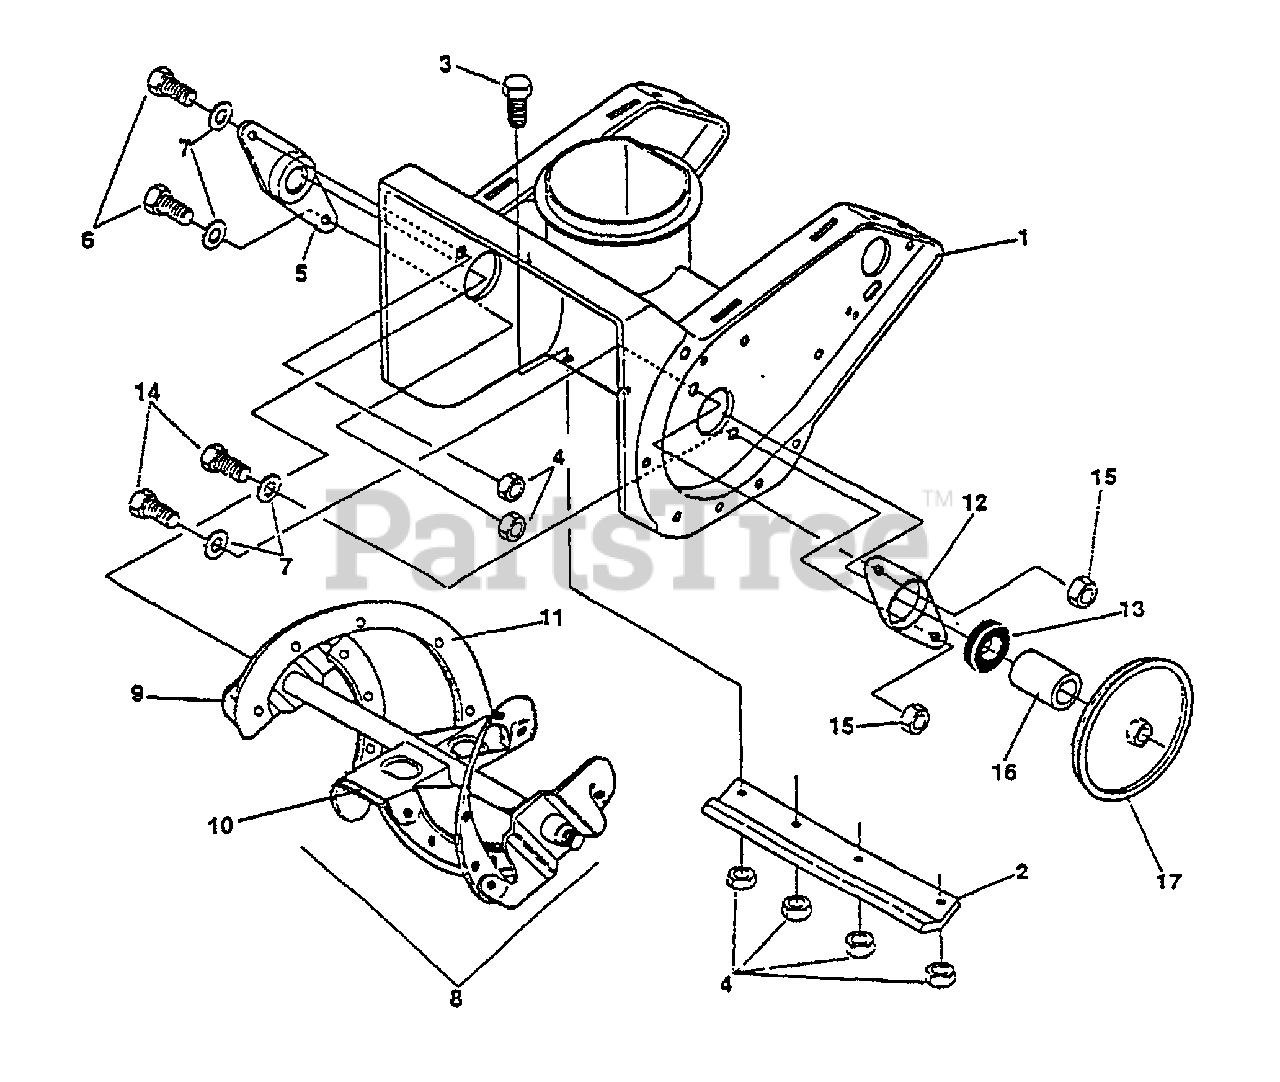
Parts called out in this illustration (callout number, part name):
1	AUGER INTAKE ASSY - 21"
2	BLADE, SCRAPER
3	SCREW 1/4"-20×0.63
4	NUT, 1/4"-20
5	BEARING, FLANGE
6	SCREW - 1/4-20×0.88"
7	WASHER
8	AUGER ASSY
8A	AUGER ASSY - 21"
9	AUGER, BLADE STRIP
10	AUGER, CENTER BLADE STRIP
11	RIVET, 0.250×.5 IN.
12	RETAINER, BEARING
13	BEARING, BALL
14	SCREW 1/4 20×.75 IN
15	NUT, 1/4"-20
16	SPACER
17	PULLEY
